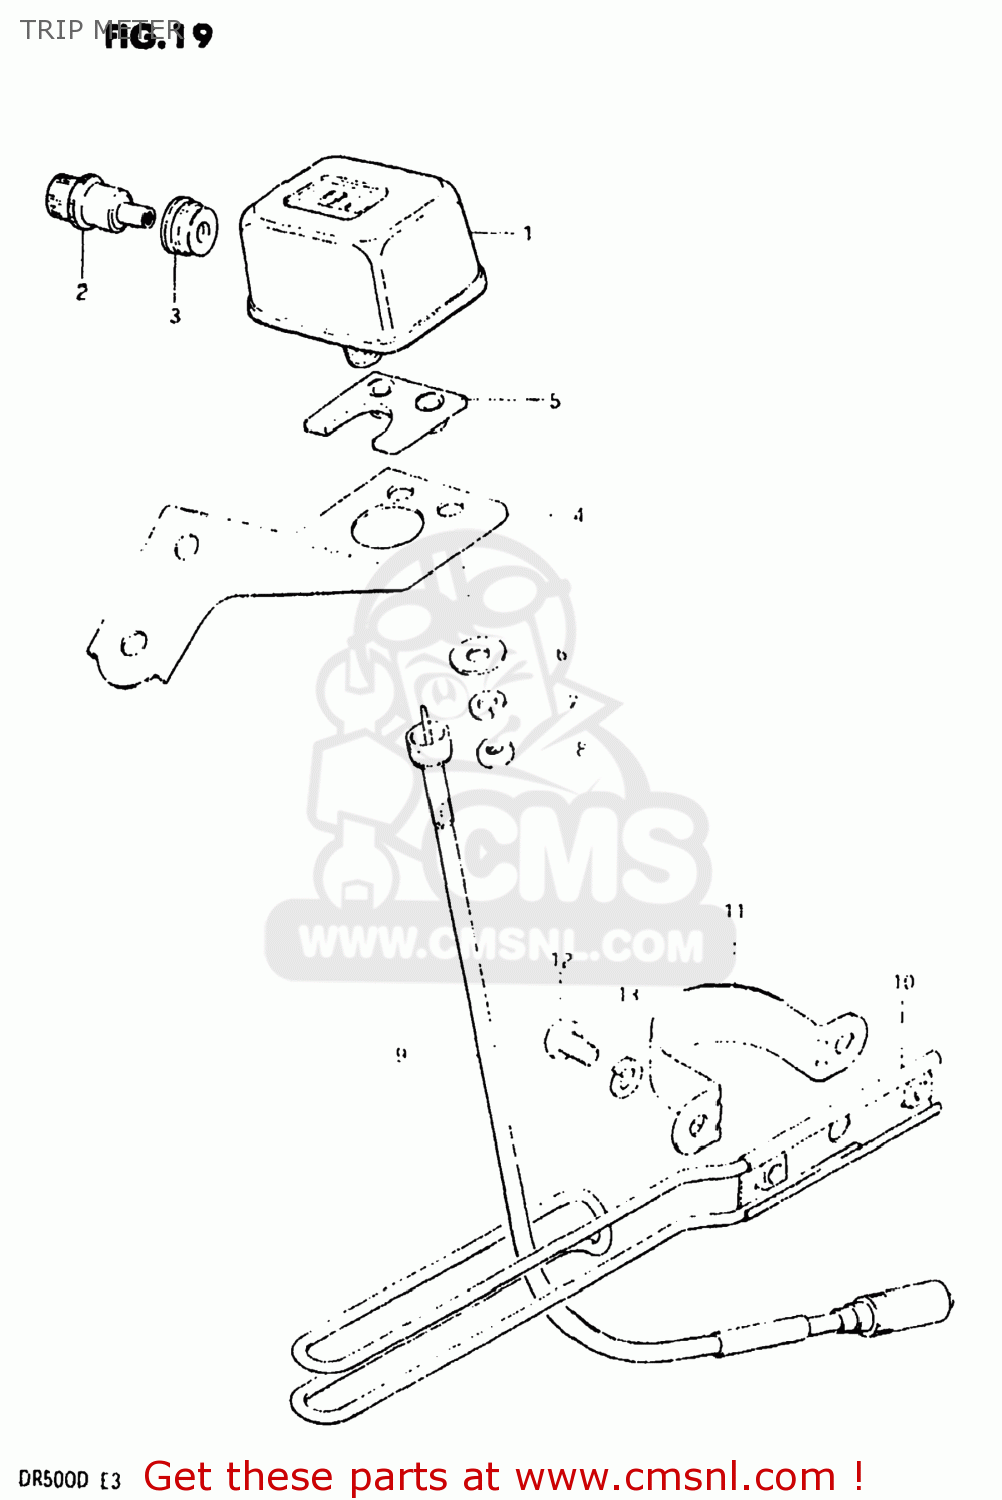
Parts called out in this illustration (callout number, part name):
1	TRIP METER
2	KNOB,TRIP METER
3	COVER,TRIPMETER KNOB
4	BRACKET,TRIPMETER
5	CUSHION,TRIPMETER
6	WASHER,METER
7	LOCK WASHER
8	NUT
9	CABLE ASSEMBLY,SPEEDOMETER
10	CLAMP,SPEEDOMETER CABLE
11	CLAMP
12	SCREW 6X12
13	LOCK WASHER
